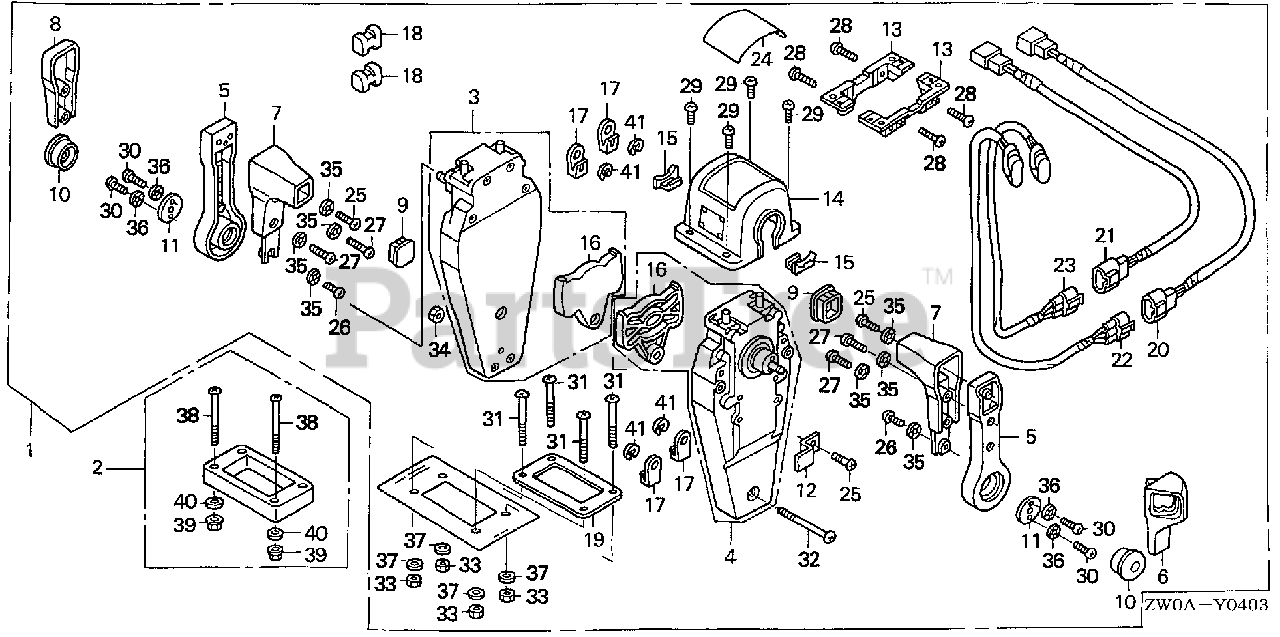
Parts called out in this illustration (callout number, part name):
1	BOX KIT, REMOTE CONTROL
2	SPACER KIT, REMOTE CONTROL BOX
3	HOUSING ASSY., L. (INNER)
4	HOUSING ASSY., R. (INNER)
5	HANDLE, REMOTE CONTROL
6	COVER, R. GRIP
7	GRIP, REMOTE CONTROL HANDLE
8	COVER, DUAL GRIP
9	CAP, GRIP
10	BUTTON, THROTTLE
11	PLATE, HANDLE
12	PLATE, CABLE CLAMP
13	BRACKET, REMOTE CONTROL
14	HOUSING, DUAL REMOTE CONTROL
15	HOUSING, LEAD
16	PLATE, DWELL
17	TERMINAL, CABLE
18	SPACER, CABLE CLAMP
19	GASKET, DUAL
20	SUB-HARNESS ASSY., POWER
21	SUB-HARNESS ASSY., POWER
22	SWITCH ASSY., POWER TRIM-TILT
23	SWITCH ASSY., POWER TRIM-TILT
24	MARK, REMOTE CONTROL (DUAL)
25	SCREW, PAN (5X16)
26	SCREW, PAN (5X10)
27	SCREW, PAN (5X20)
28	SCREW, PAN (5X18)
29	SCREW, PAN (4X10)
30	SCREW, PAN (6X18)
31	SCREW, PAN (5X40)
32	SCREW, PAN (5X55)
33	NUT, HEX. (5MM)
34	NUT, HEX. (5MM)
35	WASHER, LOCK (5MM)
36	WASHER, LOCK (6MM)
37	WASHER, PLAIN (5MM)
38	SCREW, PAN (5X65)
39	NUT, HEX. (5MM)
40	WASHER, PLAIN (5MM)
41	E-RING (6MM)
